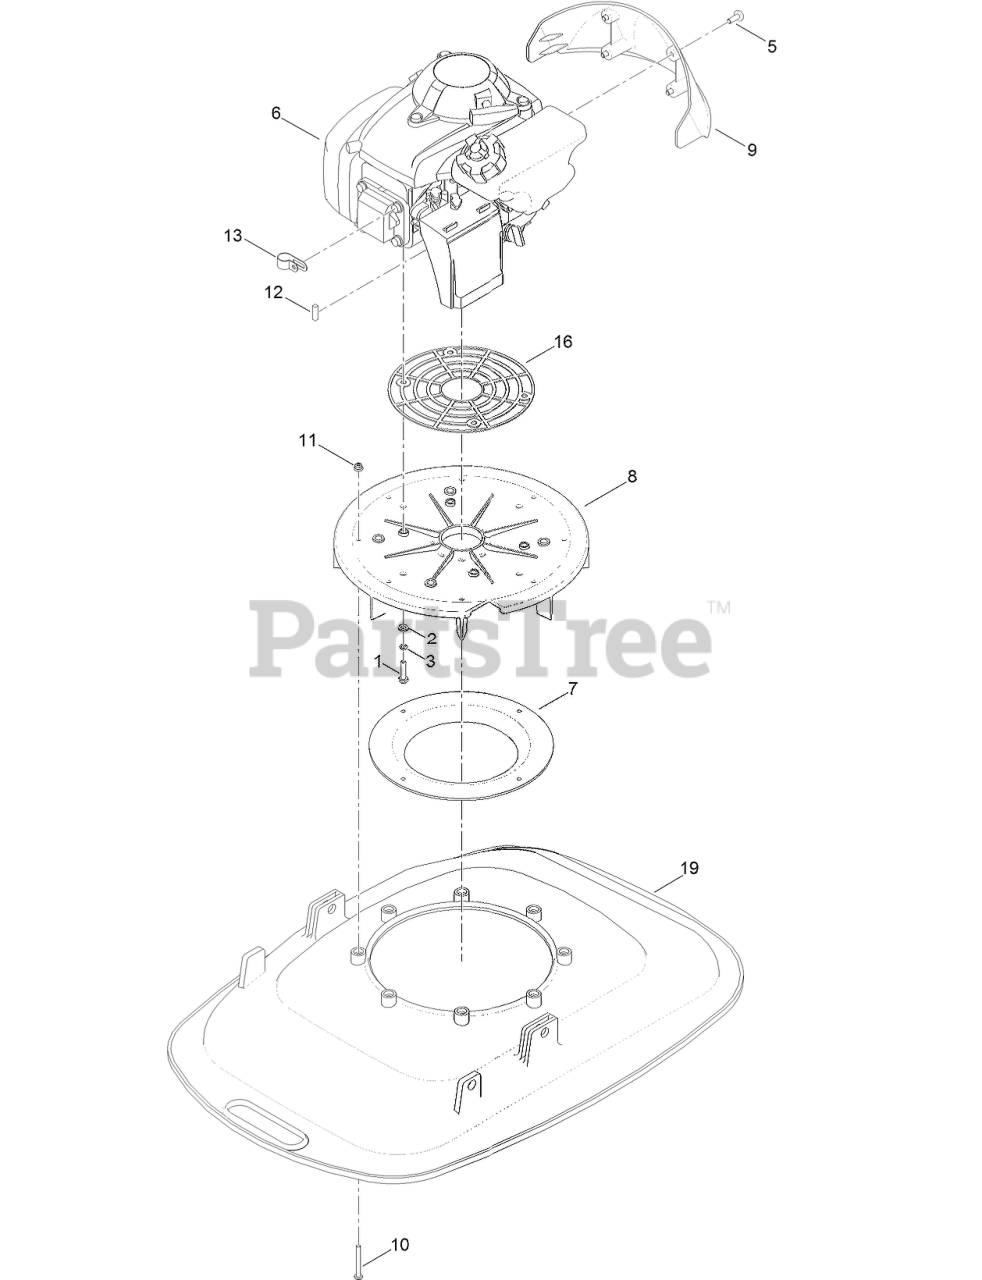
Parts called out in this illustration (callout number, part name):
1	SCREW-HH
2	WASHER-PLAIN
3	WASHER-SPRING
5	SCREW-SOC, HD
6	ENGINE-HONDA
7	BELL-MOUTH
8	PLATE-ENGINE
9	COVER-SUMP
10	SCREW-PPH
11	NUT-HHF, NY
12	KEY-DRIVE, SQUARE ENDED
13	CLIP-P, NATURAL
16	SINK-HEAT
